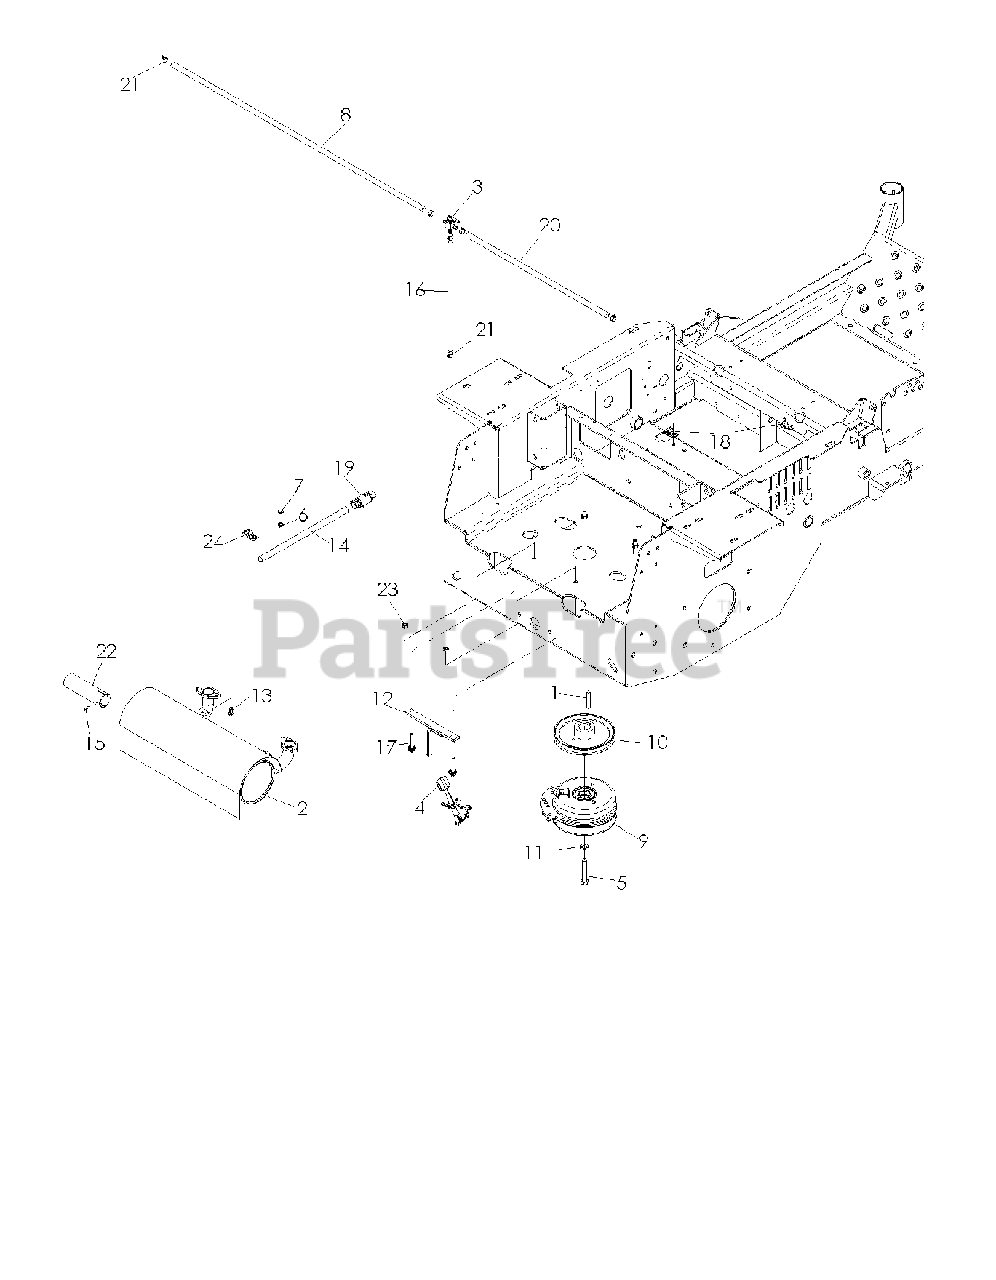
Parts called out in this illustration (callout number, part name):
1	KEY 1/4" SQ X 1 7/8"
2	MUFFLER
3	FUEL VALVE
4	CHOKE CABLE
5	BOLT 7/16F X 2 1/2
6	NUT 1/4C CENTER LOCK
7	HCS 1/4C X 3/4 HCS
8	HOSE 35"
9	ELECTRIC CLUTCH W/CABLE
11	WASHER 7/16 LOCK
12	CLUTCH TIE DOWN
13	SCREW- 1/4-20 X 5/8
14	OIL DRAIN HOSE
15	SCR #8 X 1/2 PHIL HD DRILL BLK
16	FUEL LINE 13"
17	HCS 5/16-18 X 1-3/4 SERATED
18	DOUBLE TUBE CLAMP
19	OIL DRAIN FITTING
20	FUEL LINE
21	HOSE CLAMP
22	TUBE, EXTENSION, MUFFLER
23	NUT 5/16C CENTERLOCK
